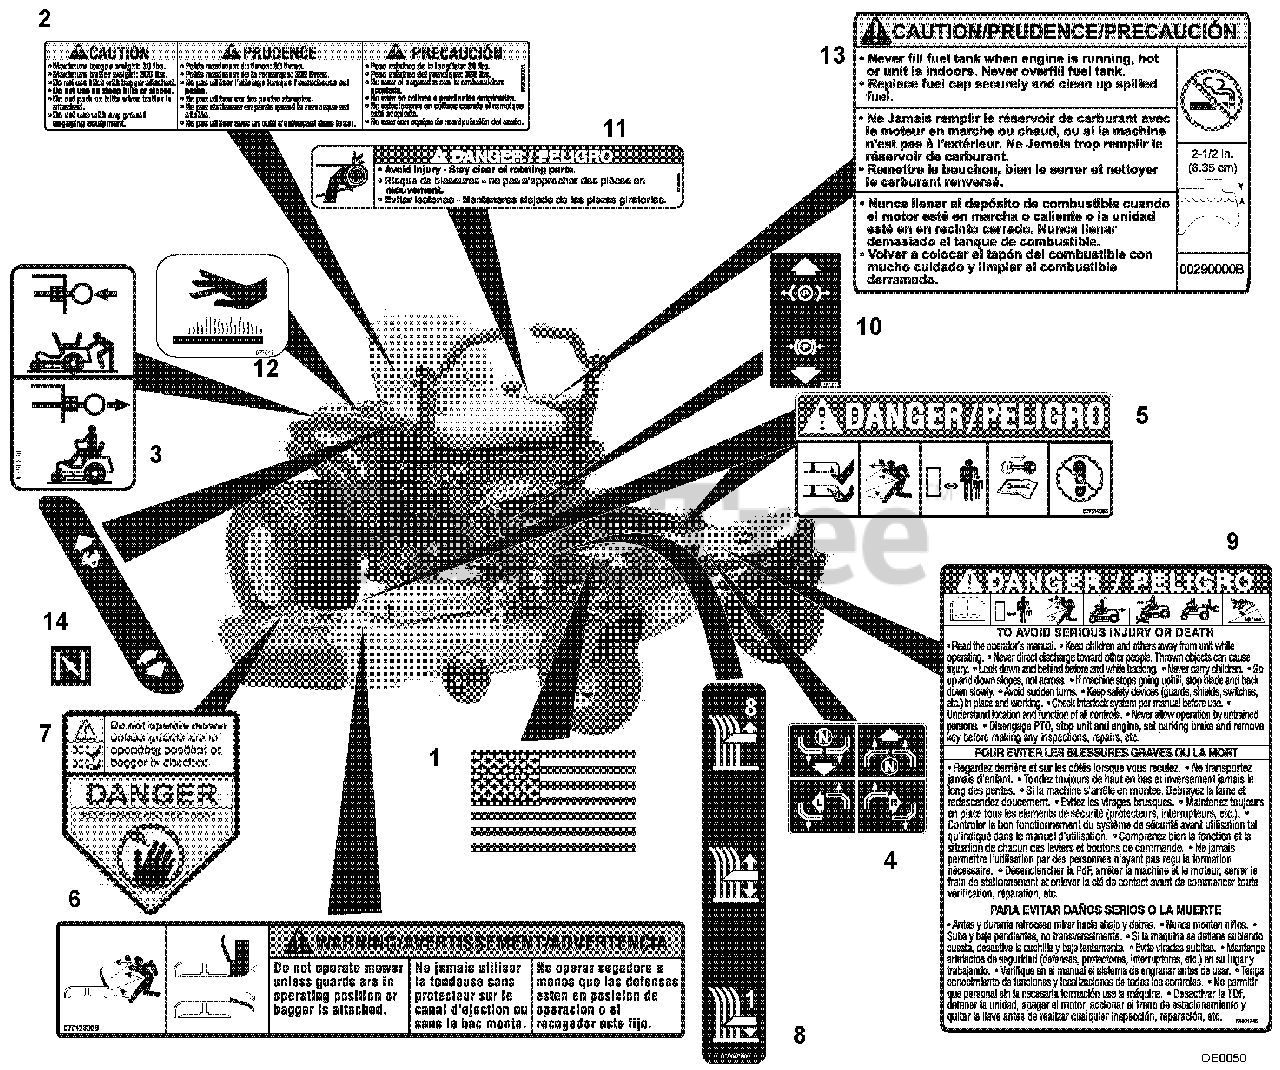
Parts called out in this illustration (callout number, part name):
1	DECAL, AMERICAN FLAG
2	DECAL, TRAILER HITCH
3	DECAL, TRANSMISSION DISCONNECT
4	DECAL, INSTRUCTIONAL-STEERING
5	DECAL, MOWER PAN DANGER
6	DECAL, WARNING
7	DECAL, CPSC DANGER
8	DECAL,CUT HEIGHT
9	DECAL, DANGER BILINGUAL
10	DECAL, PARKING BRAKE LEVER
11	DECAL- DANGER
12	DECAL, HOT SURFACE
13	DECAL,FUEL WARNING
14	DECAL, SPEED CONTROL
